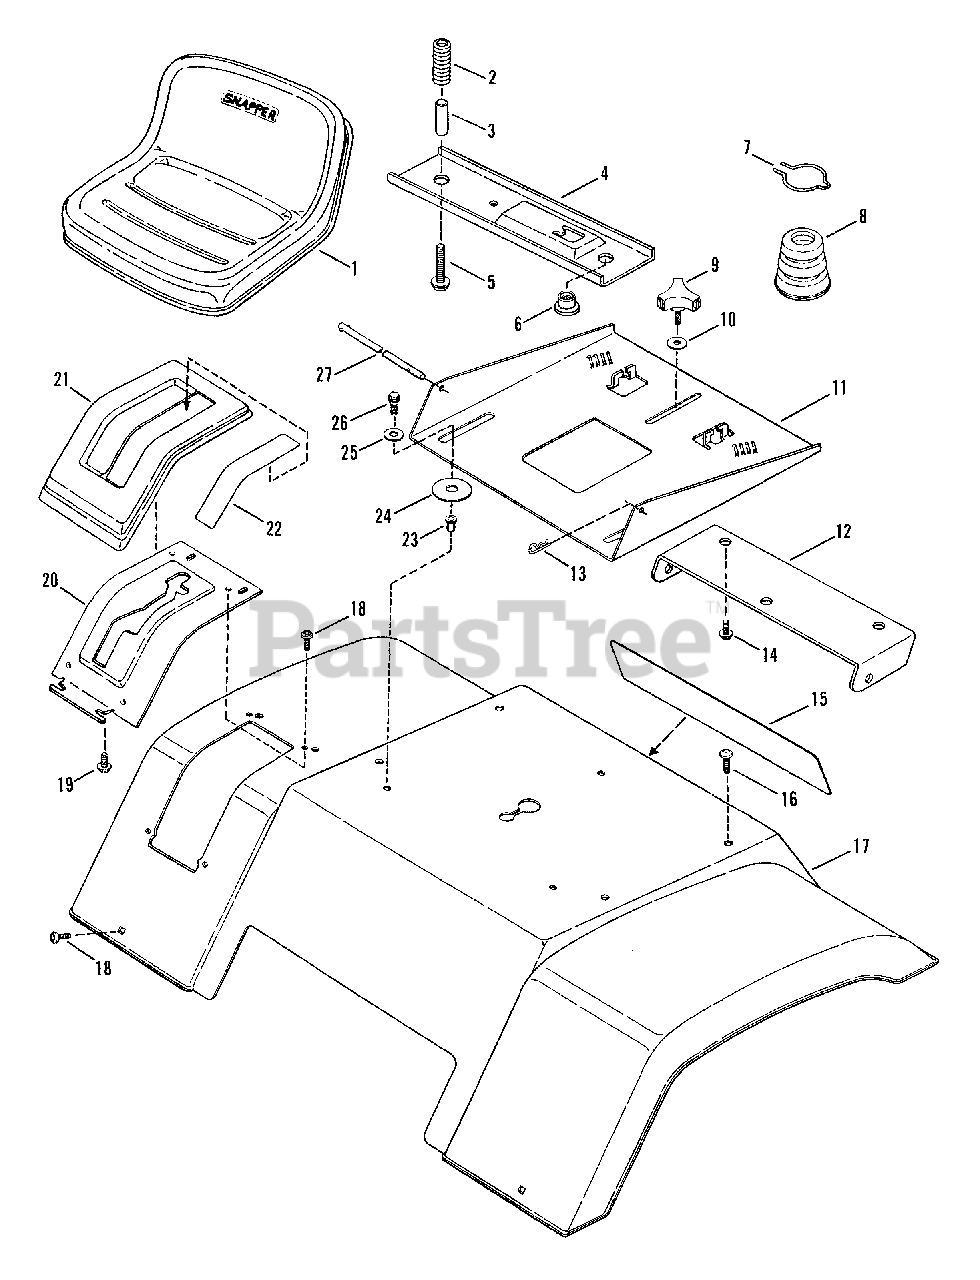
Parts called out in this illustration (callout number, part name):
1	SEAT, Operator's
2	SPRING, Seat Switch
3	SPACER, Seat
4	HOLDER, Seat Switch
5	BOLT, 5/16-18 x 2" Hex Flange Lock
6	BUSHING, Seat
7	CLIP, Seat Bumper
8	CUSHION, Seat
9	KNOB, Seat Adjustment
10	WASHER
11	SUPPORT, Seat
12	BRACKET, Seat Support
13	PIN, Hair
14	BOLT, 5/16-18 x 1/2" Hex Flange Lock
15	DECAL, SNAPPER, 8" Molded Logo (Teal)
15	DECAL, SNAPPER, 8" Molded Logo (Green)
16	SCREW, 5/16-18 x 7/8" Torx Head, Self-Tapping
17	FENDER, Rear
18	SCREW, 1/4-20 x 5/8" Torx Head, Self-Tapping
19	SCREW, #10-16 x 1/2" Self-Tapping
20	DETENT, Shift
21	COVER, Shift Detent
22	DECAL, Shift Cover
23	RIV-NUT, 5/16-18
24	SPACER
26	SCREW, Shoulder, 5/16-18 x 3/4"
27	ROD, Seat Hinge
